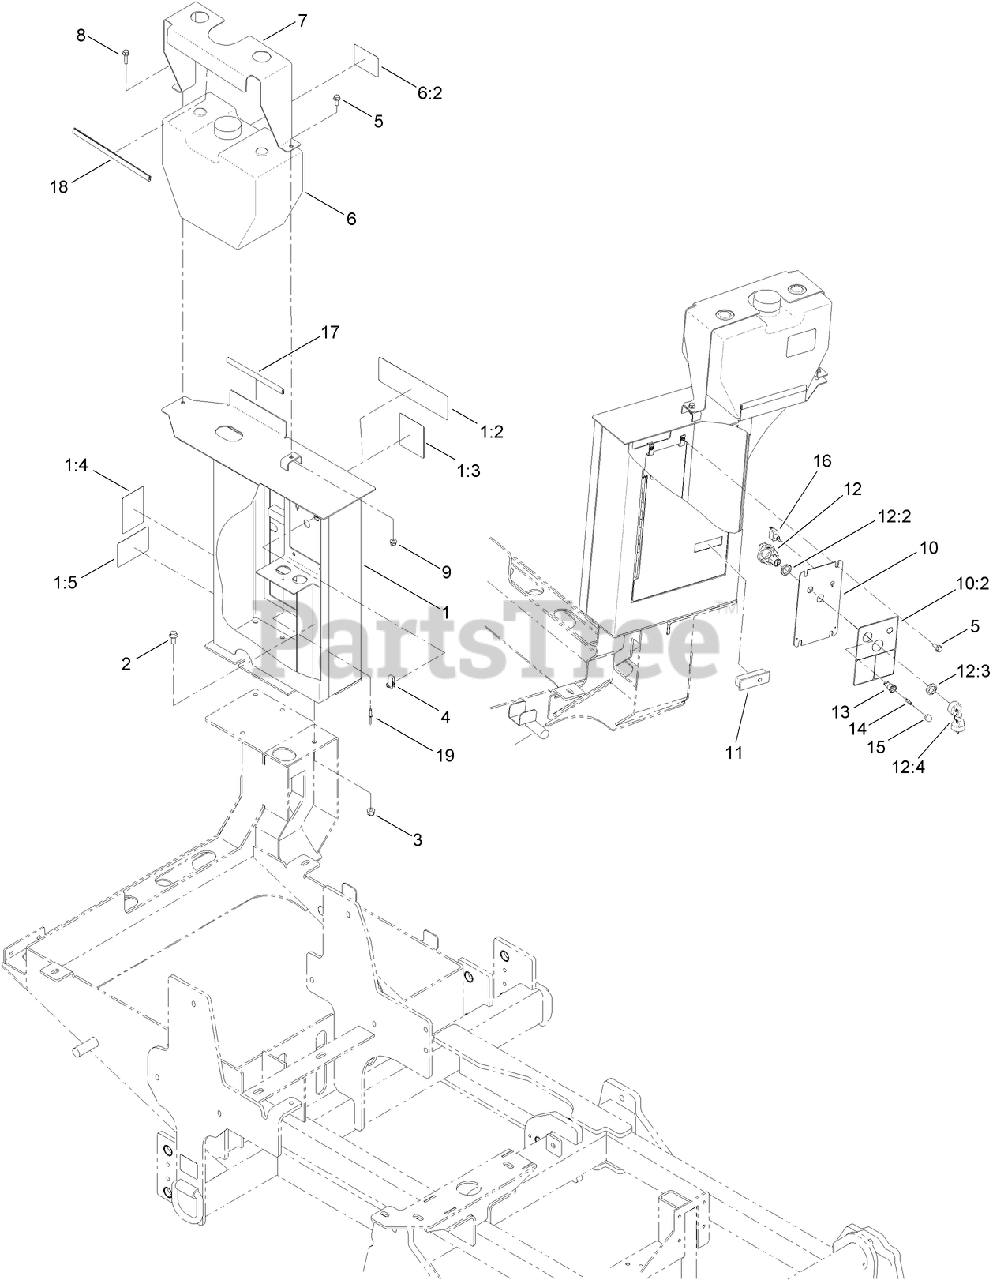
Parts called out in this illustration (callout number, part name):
1	REAR CONTROL BOX ASM
1:2	DECAL-SAFETY
1:3	DECAL-DANGER, NO RIDERS (REAR)
1:4	DECAL-DANGER, BACK UP
1:5	DECAL-RAISE AND LOWER
2	SCREW-HHF
3	NUT-LOCK, NI
5	SCREW-HHF
6	TANK COOLANT ASM
6:2	DECAL-ANTIFREEZE
7	BRACKET-BOTTLE, ANTI-FREEZE
8	SCREW-HHF
9	NUT-LOCK, HHF
10	REAR CONTROL PANEL ASM
10:2	DECAL-REAR CONTROL
11	LATCH-TRIGGER, RAISED (W/LOCK)
12	IGNITION SWITCH ASM
12:2	NUT-HEX
12:3	NUT-FACE
12:4	IGNITION KEY SET
13	TYPE T-2 SOCKET ASM
14	LAMP-LED
15	LENS-DOME, FLUTED AMBER (TYPE T2)
16	SWITCH-TOOGLE, SPST, ON-OFF (SEALED)
17	TRIM-TANK
18	TRIM-TANK
19	RIVET-POP
